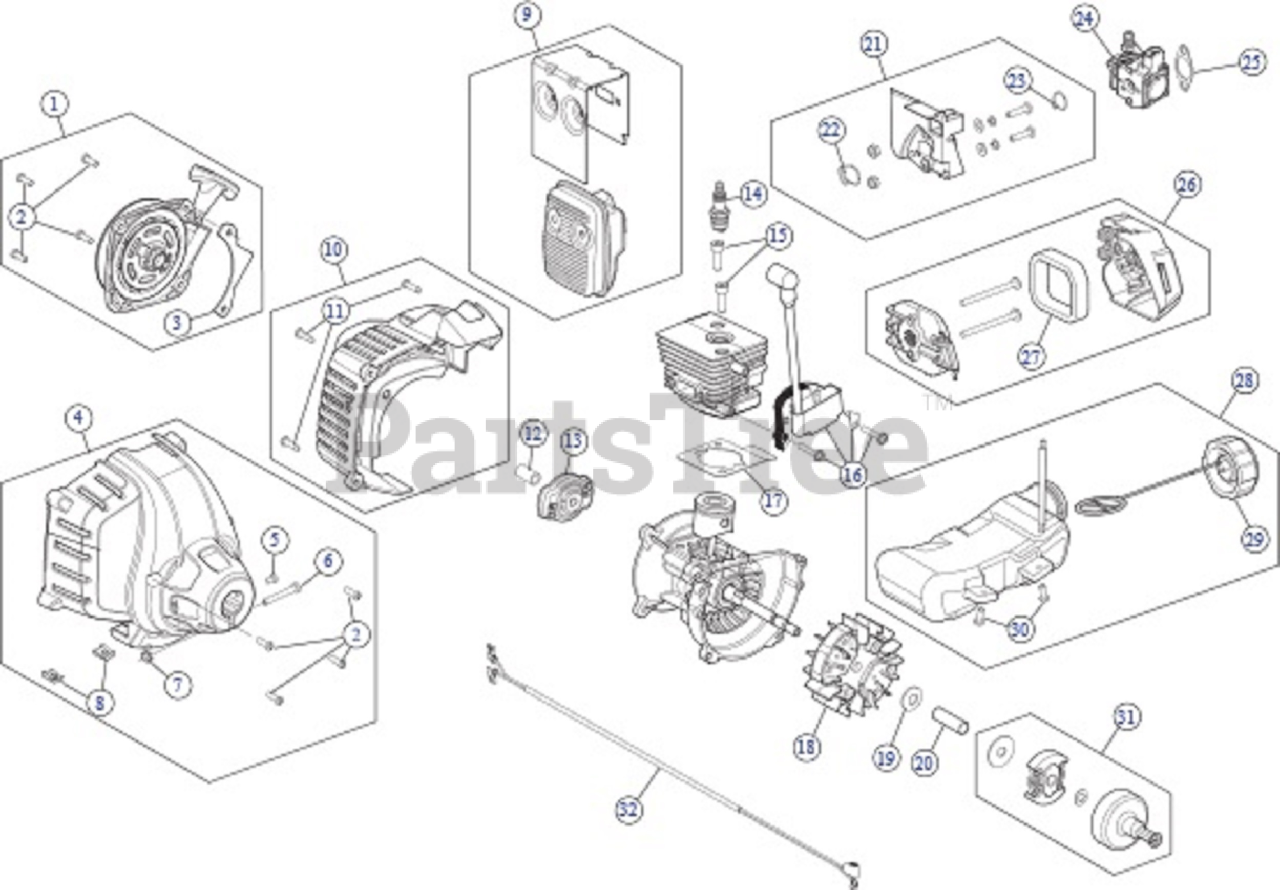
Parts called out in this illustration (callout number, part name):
1	Starter Assembly (Incl. 2 & 3)
2	Starter Screw
3	Starter Assembly Guard (Incl. 2)
4	Clutch Cover Assembly (Incl. 2, 5 - 8)
5	Anti-Rotation Screw
6	Clamp Screw
7	Clamp Nut
8	U-Shaped Nut
9	Muffler Assembly
10	Rear Engine Cover (Incl. 11)
11	Cover Screw
13	Pawl Assembly
14	Spark Plug
15	Cylinder Bolt
16	Module Assembly
17	Cylinder Gasket
18	Flywheel Assembly
21	Insulator Assembly (Incl. 22 & 23)
22	Insulator O-Ring
23	Carburetor O-Ring
24	Carburetor
25	Carburetor Gasket
26	Air Cleaner Assembly (Incl. 27)
27	Air Cleaner Filter
28	Fuel Tank Assembly (Incl. 29 & 30)
29	Fuel Tank Cap
30	Fuel Tank Screw
31	Clutch Assembly
32	Lead Wires
